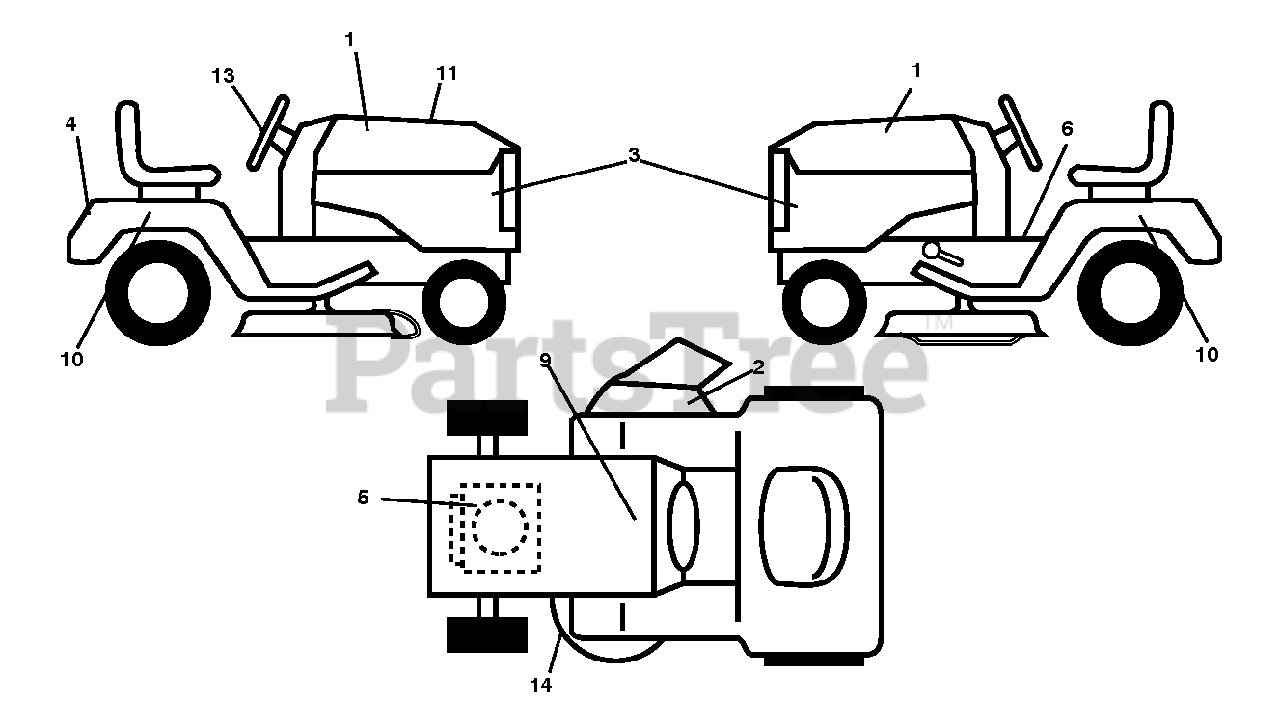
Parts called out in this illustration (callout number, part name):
1	DECAL.HOOD.POULAN.PRO.SET
2	DECAL.WARN.KEEP.HAND.AWAY
4	DECAL.REAR.FNDR.LOGO.POULAN.PR
6	Fender Warning Decal, English
9	DECAL BTRY SYMBOLS
10	DECAL.FEND.SD.SET.HYD.P-PRO
14	DECAL V BELT SCHEMATIC
